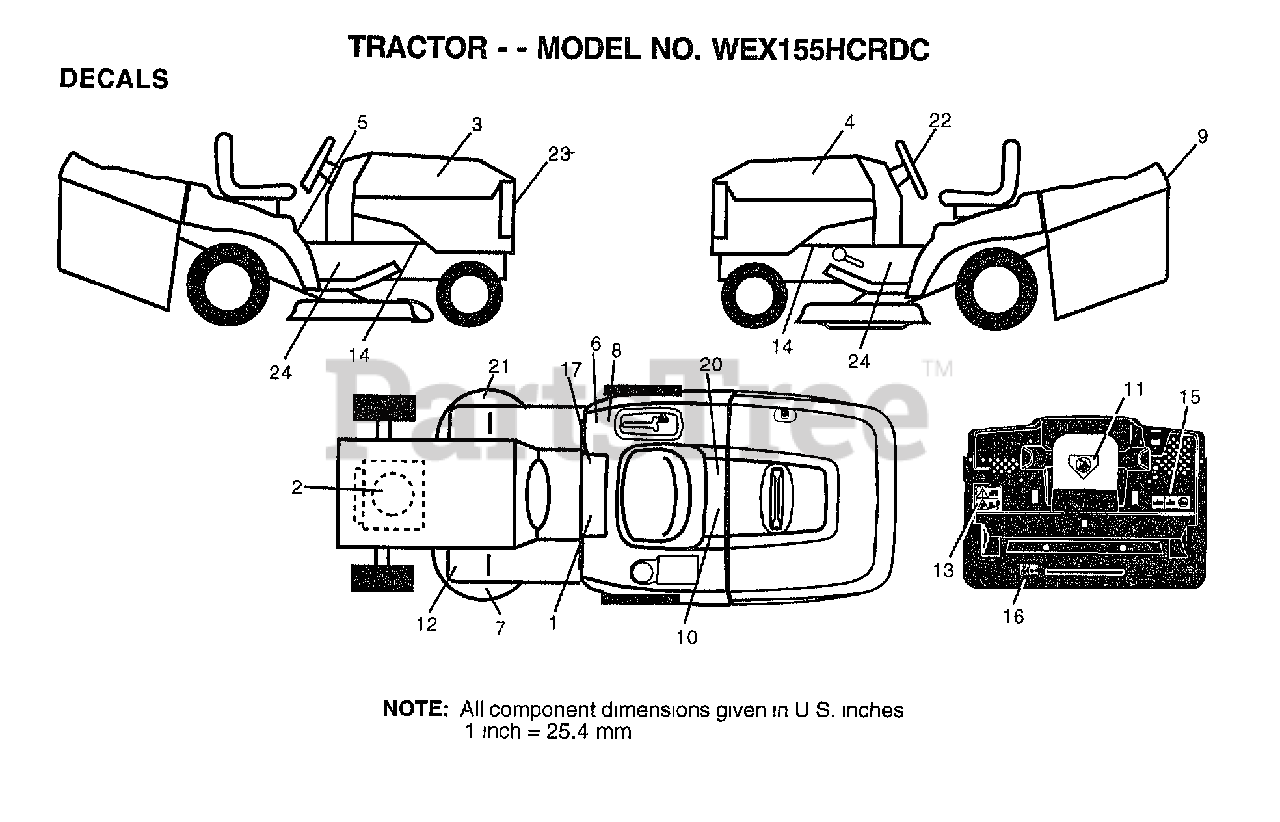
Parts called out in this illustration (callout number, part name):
1	DECAL.READ.O.MANU
3	DECAL.HOOD.RH.
4	DECAL.HOOD.LH
5	DECAL.READ.O.MANU
7	DECAL, DECK GRASSEATER
8	DECAL.EURO.ST.CE.
9	DECAL.FENDER.LOGO
10	DECAL.BATRY.3-3908
11	DECAL.DANGER.CUTF
12	DECAL-BRAKE/CLUTC
13	DECAL.WARNING.BACKPLATE.CRD
14	"DECAL CHASSIS,HOT"
15	DECAL, OPER BAG
16	DECAL.DRAWBAR.LDL
17	DECAL BRAK PARK
20	DECAL.BYPASS.FENDER.CRD.LT.YT
21	DECAL.DECK.HEX.BELT
22	DECAL, INS STRG WH
23	DECAL, GRILLE LENS
24	DECAL.PANEL.SD
